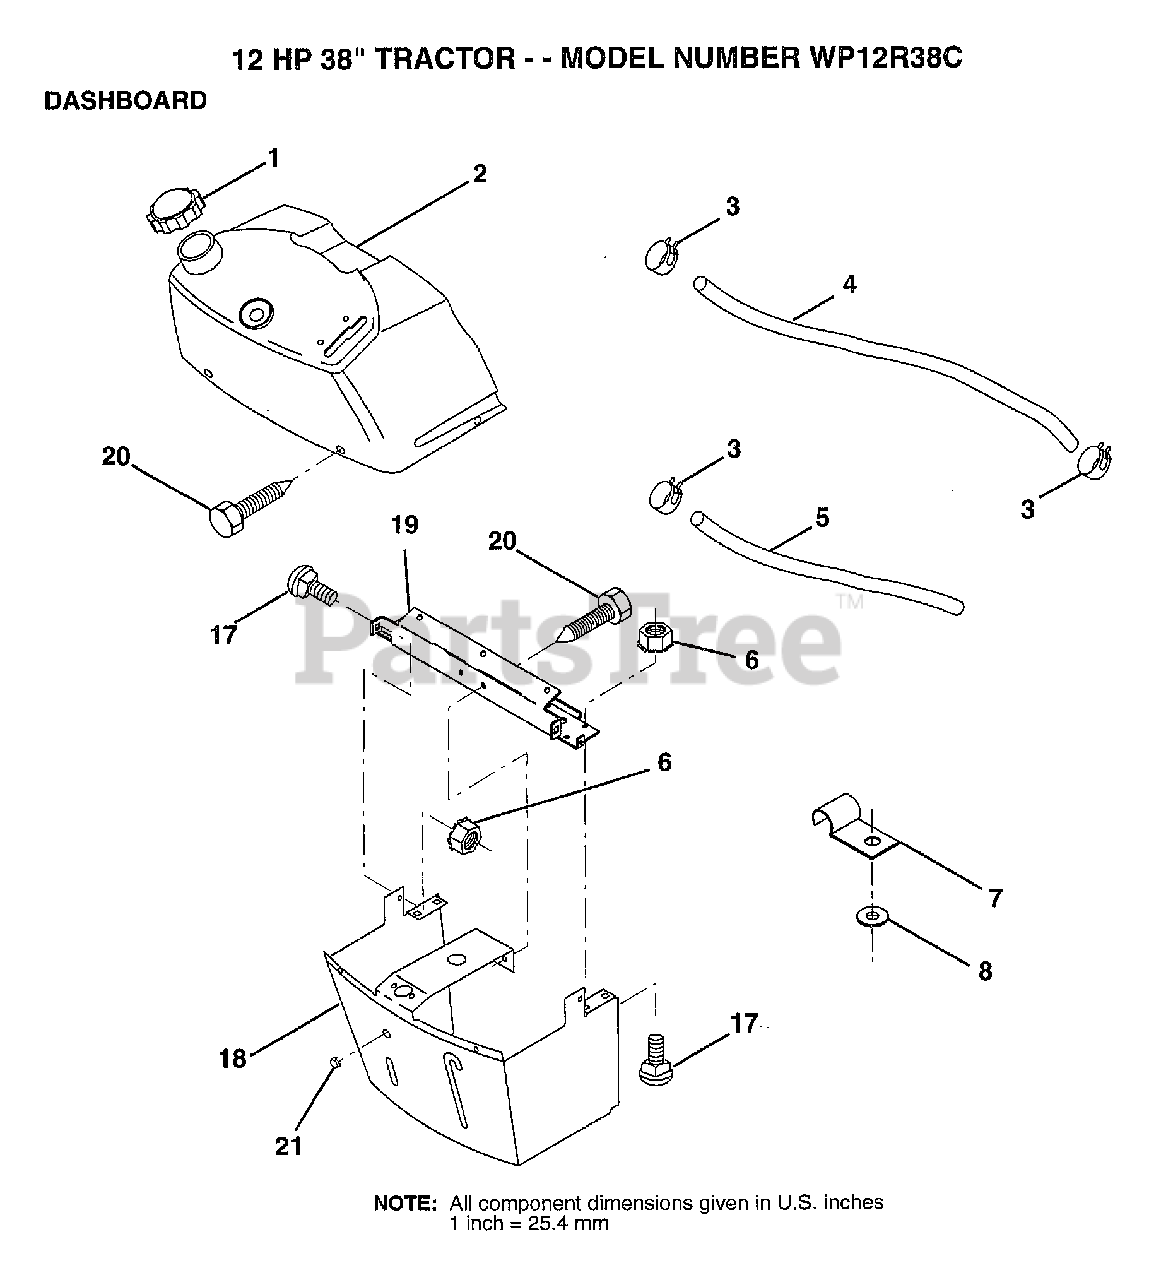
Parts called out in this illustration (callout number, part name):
1	CAP BLK FUEL LR
2	TANK.ASM.DASH.LR
3	HOSE CLAMP
5	FUEL LINE T
6	NUT
7	CLIP T
8	WASHER PM
17	BOLT
18	SUPT ASM DASH
19	CROSS BRACE
20	SCREW.1/4-20X1/2
21	PLUG DOME
